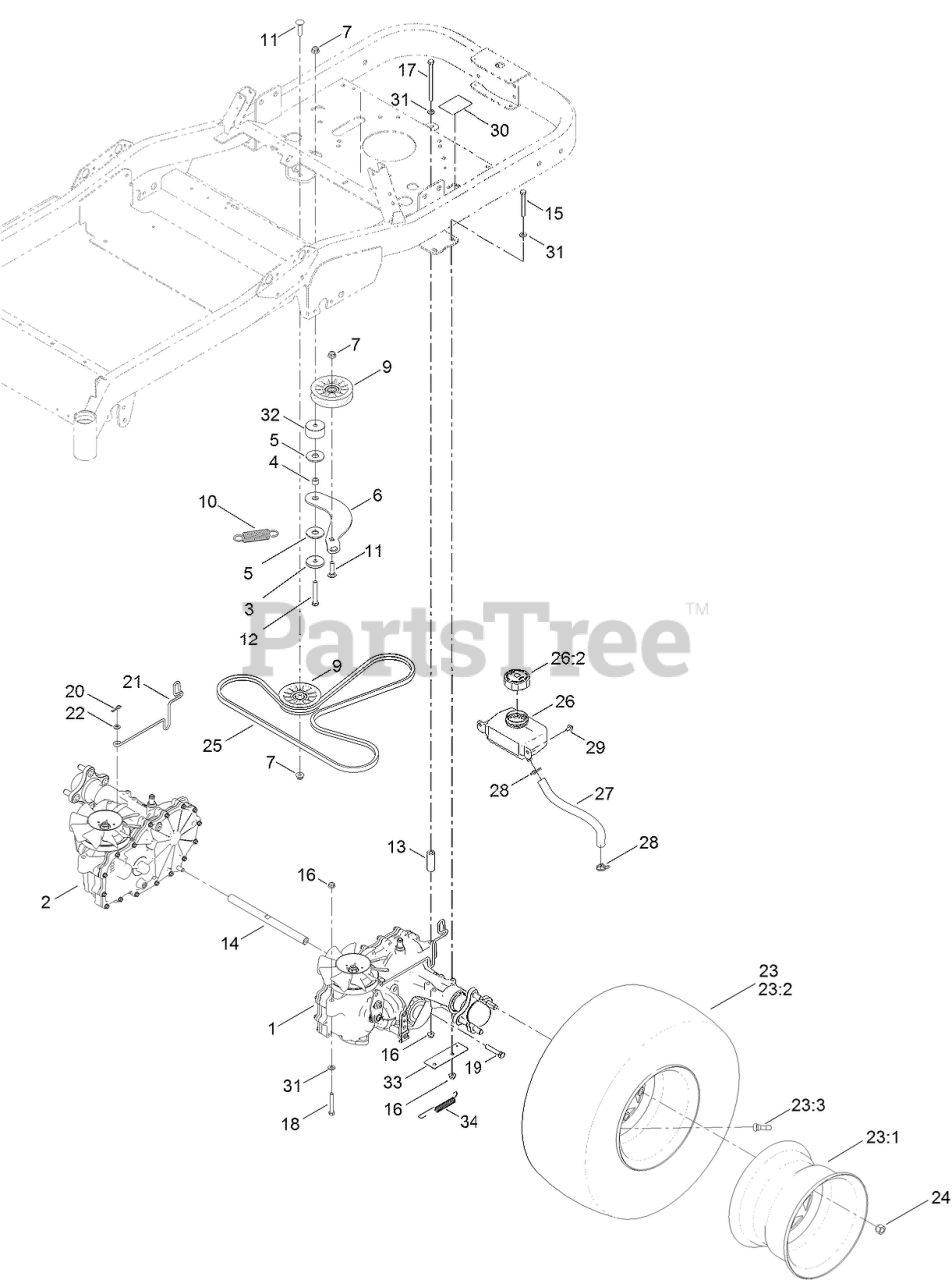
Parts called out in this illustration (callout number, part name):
1	LH HYDRO TRANSMISSION ASM
2	RH HYDRO TRANSMISSION ASM
3	WASHER-PLAIN
4	SPACER
5	WASHER-FRICTION, COMPOSITE
6	ARM-IDLER
7	NUT-HF, NI
9	PULLEY-IDLER, FLAT
10	SPRING-EXTENSION
11	SCREW-CARR
12	SCREW-HH
13	SPACER-HYDRO
14	SHAFT-CROSS, HYDRO
15	SCREW-HH
16	NUT-HF, NI
17	SCREW-HH
18	SCREW-HH
19	SCREW-HH
20	PIN-COTTER
21	ROD-BYPASS
22	WASHER-FLAT
23	TIRE AND WHEEL ASM
23:1	RIM-10 INCH
23:3	STEM-VALVE
24	NUT-LUG
25	V-BELT
26	HYD RESERVIOR ASM
26:2	CAP-RESERVOIR, HYD
27	HOSE-OVERFLOW
28	CLAMP-HOSE
29	SCREW-HHFTF
30	DECAL-BYPASS
31	WASHER-PLAIN
32	SPACER
33	PLATE-SPRING
34	SPRING-EXTENSION
